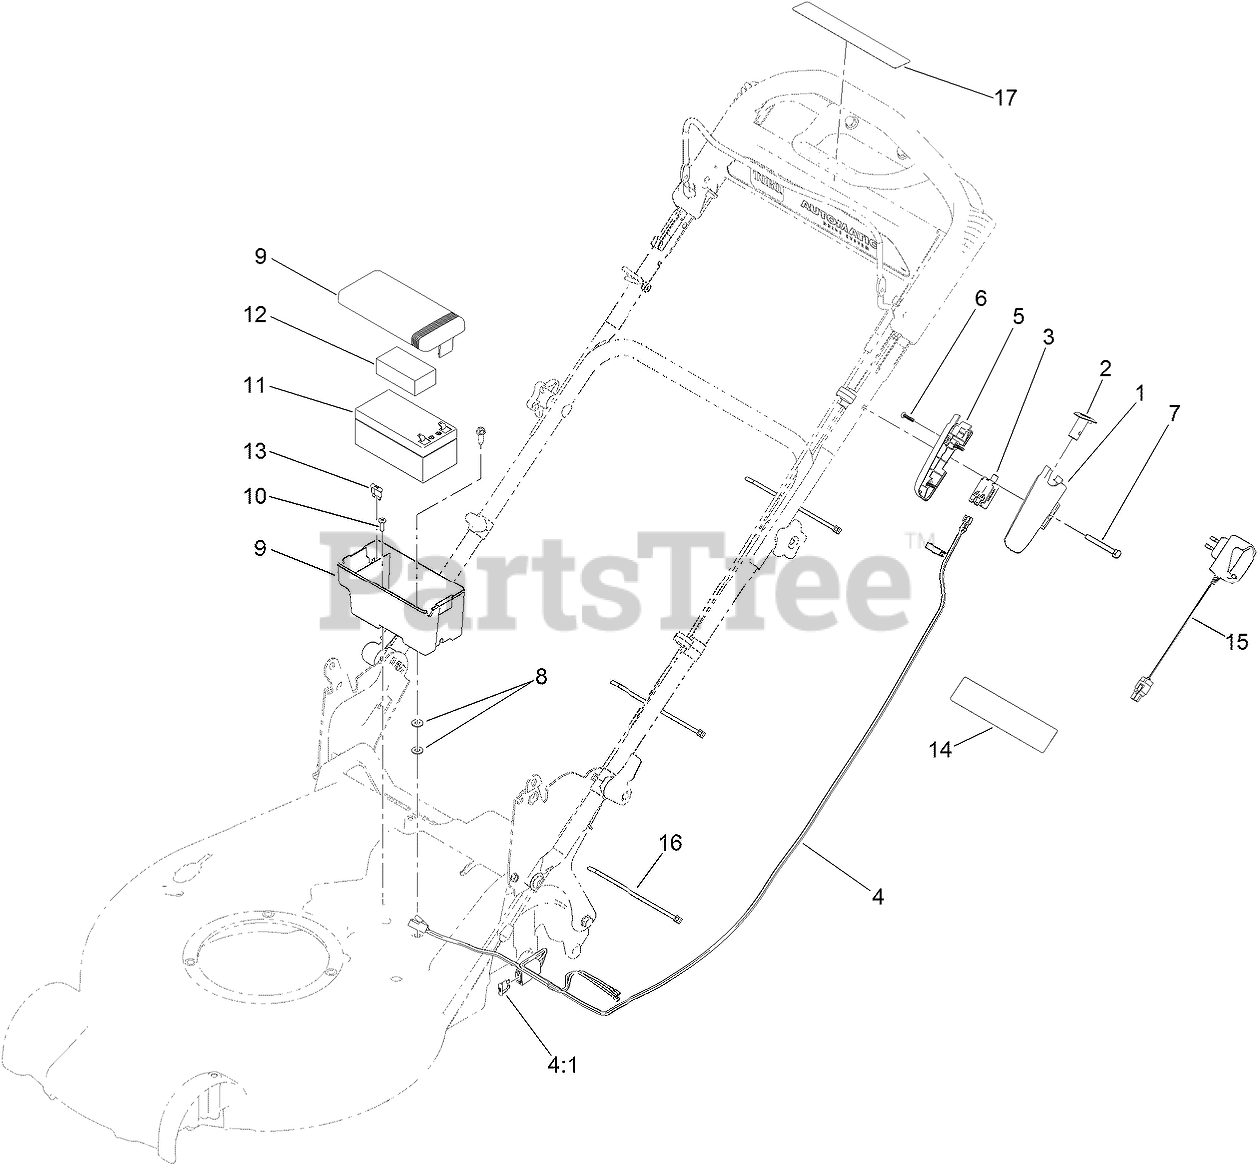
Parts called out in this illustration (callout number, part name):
1	HOUSING-SWITCH, LH
2	BUTTON-SWITCH
3	SWITCH-PUSH BUTTON
4	HARNESS-WIRE
4:1	FUSE-40 AMP
5	HOUSING-SWITCH, RH
6	SCREW-PPH
7	SCREW-HH
8	WASHER-FLAT
9	BATTERY BOX ASM
11	BATTERY-WET
12	FOAM-BATTERY, TOP
13	FUSE-40 AMP
14	DECAL-WARNING
16	TIE-CABLE
17	DECAL-BUTTON, PUSH
